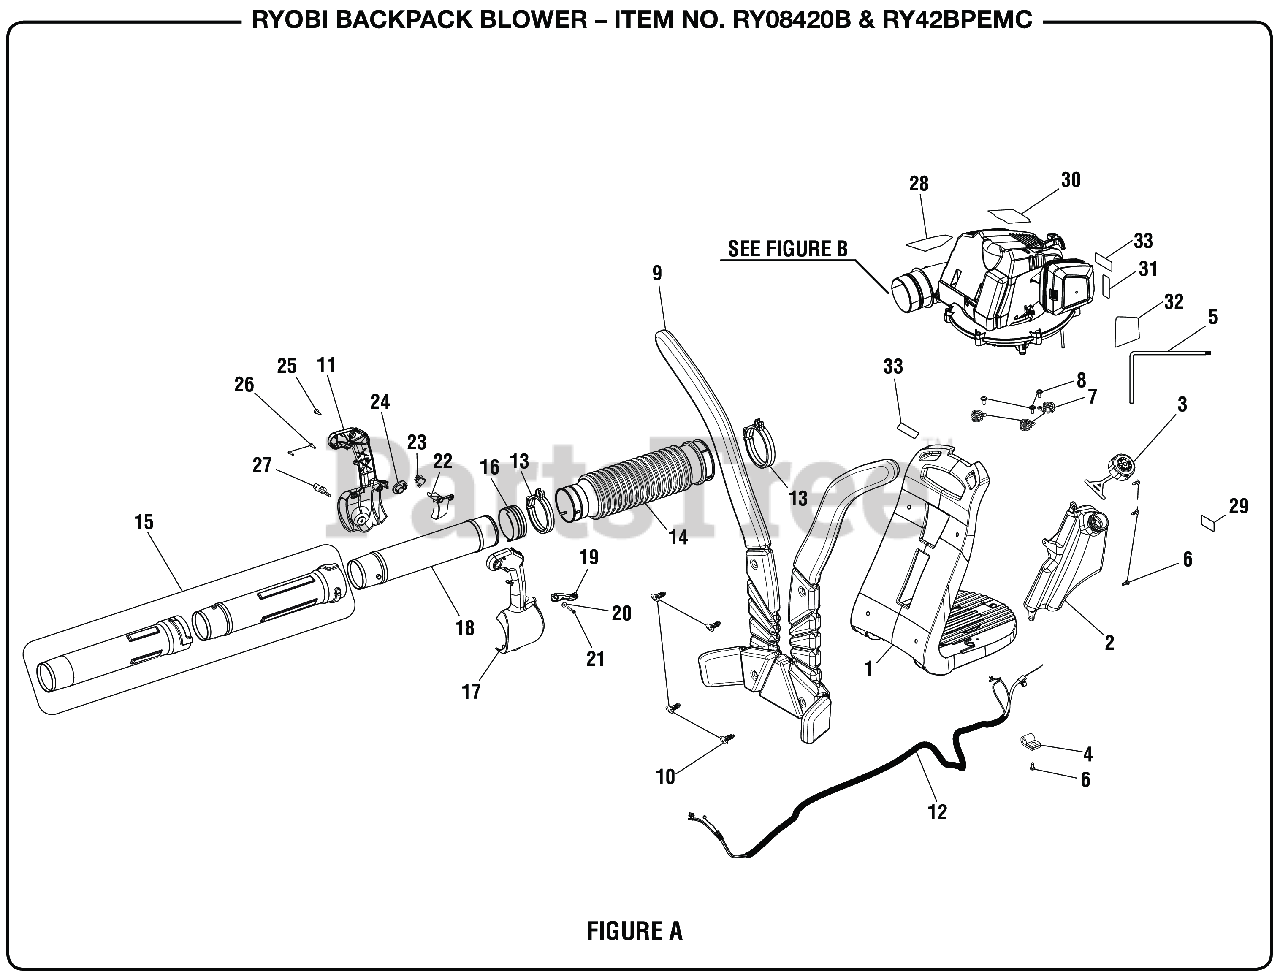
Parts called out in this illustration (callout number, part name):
2	Fuel Tank Assembly
3	Fuel Cap Assembly (Inc. Tether)
4	Cable Clamp
5	Wrench (L-25)
6	Screw (10-14 x 1/2 in., Torx Truss Hd. T.F.)
8	Screw (10-14 x 16 mm)
10	Harness Snap Fastener
11	Right Hand Handle
12	Throttle Cable
13	Clamp Assembly Kit
15	Sweeper Nozzle & Upper Blower Tube Assembly
16	Upper Blower Tube Bushing
17	Left Hand Handle
18	Throttle Control Handle
19	Cruise Lever
20	Washer (ID 4.3 x OD12 x 1.5t)
21	Cruise Lever Screw (M8-14 x 25 mm, Special T20 Truss Hd.)
23	Stop Switch (Momentary Contact)
24	Cruise Control Actuator
25	Screws (10-14 x 3/4 in., T25 Torx Pan Hd. T.F.)
26	Screw (M4 x 16 mm, T20 Torx Pan Hd. S.T.)
27	Blower Knob (1.35 in [34.3 mm])
28	Combustion Warning Label
29	Warning Label
30	Model Label
31	Choke Label
32	Start Instructions Label
33	Logo Label
